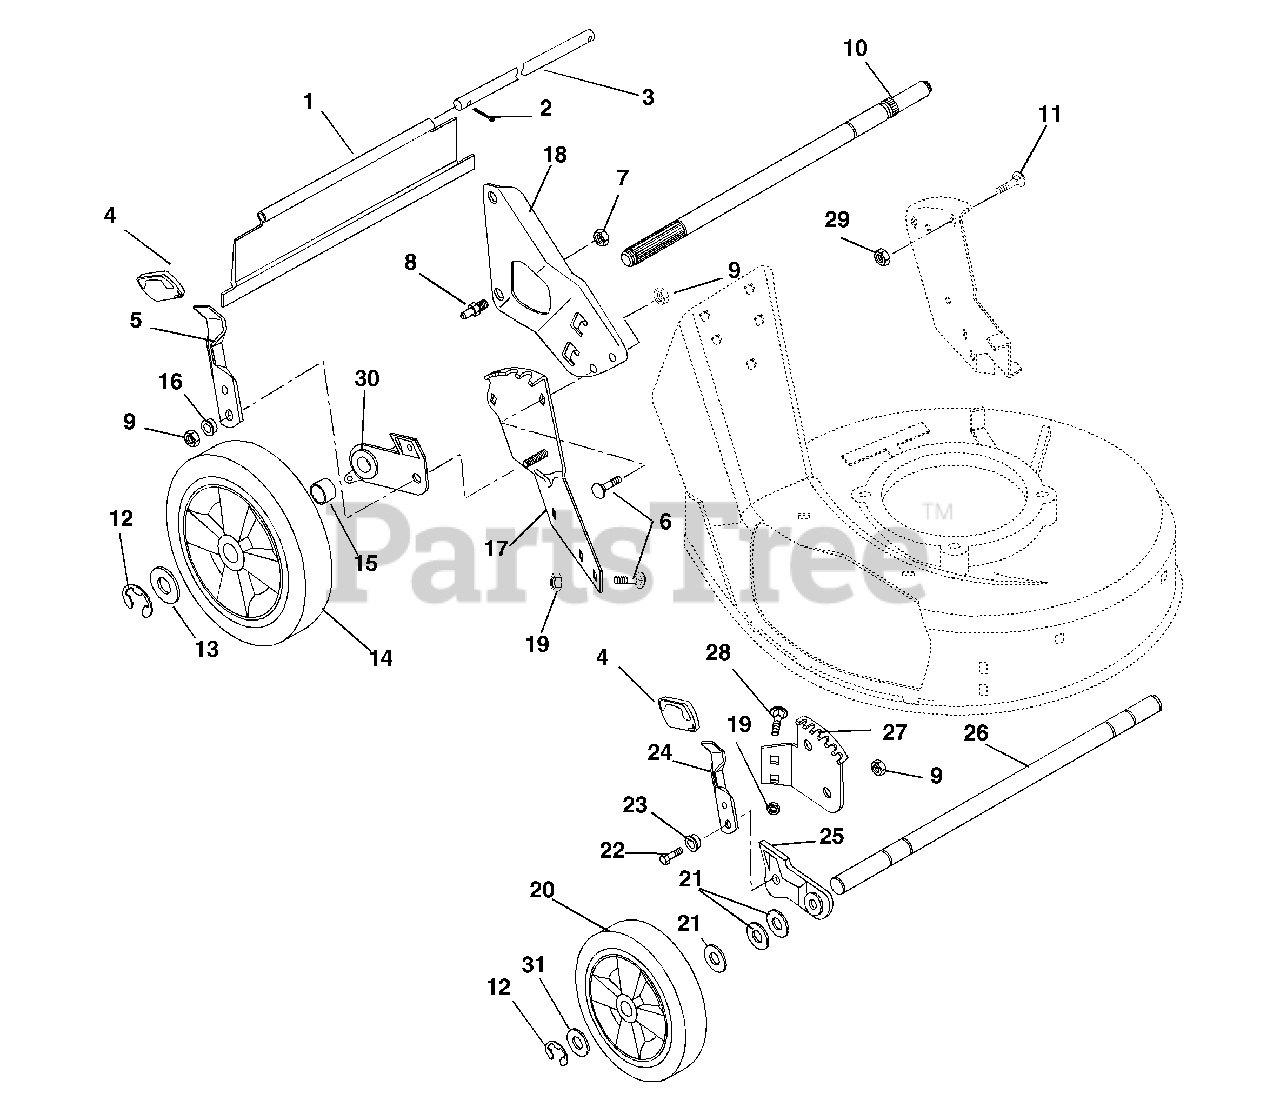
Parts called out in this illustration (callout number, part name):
1	REAR PROTECTIVE GUARD, S.P.
1	REAR PROTECTIVE GUARD, PUSH
2	@PIN-CTR .06X.50 EXTPRSQCT YWZ
3	ROD
5	HEIGHT ADJUSTMENT LEVER
6	@BLT-RHDSSQNK .31-18X.62 G5YZ
7	@NUT-LK-CTR .38-16 YWZC
8	HANDLEBAR STUD
9	@NUT-LK-CTR .31-18 YWZC
10	REAR AXLE,5/8 DIA
10	REAR AXLE-PUSH MOWER MM
11	BLT-RDHDSQNK .31-18X1.0 SHTYZ
12	RG-RTNG-EXT .500X.042 (E)
13	WSHR-FL-STL .505X.880X.072 YWZ
14	WHL, LH 10.50"
14	WHL, RH 10.50"
14	10 1/2 TIRE SKIN
14	TIRE, REAR 10X1.75 #6 GRAY
15	SPACER TUBE, SELF PROPEL
15	SPACER TUBE,PUSH LH
15	SPACER TUBE PUSH RH
16	BSHG-FLG .32X.500X.344X.880
17	QUADRANT, REAR LH
17	QUADRANT, REAR RH
18	RH HANDLEBAR MTG. BRKT
18	LH HANDLEBAR MTG. BRKT
19	@NUT-SPNLK-FLG .312-18 YWZC
20	WHL 7.50" .50 BORE, 1.50 HUB
20	TIRE, FRONT 7X1.50
21	WSHR-FL-STL .52X.827X.062 YWZC
22	@BLT-HEX .31-18X1.00 GR5 YWZC
23	BSHG-FLG .32X.500X.344X.880
24	FRONT HEIGHT ADJUSTMENT LEVER
25	LEFT ADJUSTOR BRACKET ASSEMBLY
25	RIGHT ADJUSTOR BRACKET ASSEMBL
26	FRONT AXLE
27	FRONT QUADRANT, LH
27	FRONT QUADRANT, RH
28	@BLT-RDHDSQNK .31-18X.50 G5YZ
29	@NUT-LK-NYL .312-18 YWZC
30	REAR ADJUSTMENT BRACKET L.H.
30	REAR BRACKET & BEARING ASSY RH
30	REAR BRACKET & BEARING ASSEMBL
31	WSHR-FL-STL .505X.880X.072 YWZ
